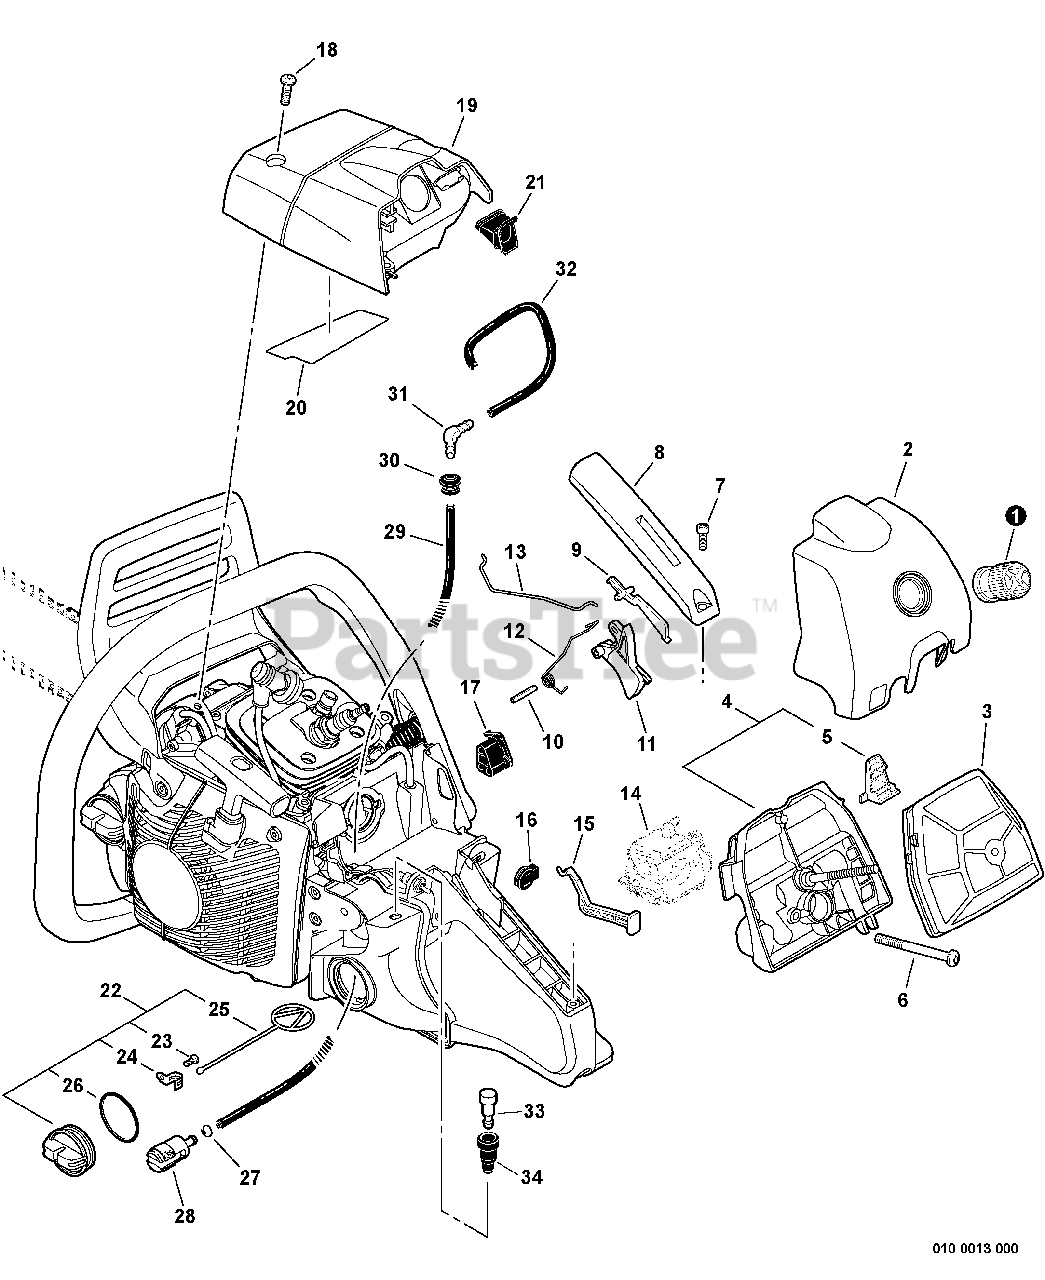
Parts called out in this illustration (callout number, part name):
1	KNOB, AIR FILTER COVER
2	COVER, AIR FILTER
3	FILTER ASSY, AIR
4	CASE ASSY, AIR FILTER
5	SHUTTER, AIR
6	BOLT, TORX 5×50
7	BOLT, TORX 4×12
8	COVER, HANDLE
9	LEVER, THROTTLE LOCKOUT
10	PIN, SPRING 4×25 SUS
11	TRIGGER, THROTTLE
12	SPRING, TORSION
13	ROD, THROTTLE
14	CARBURETOR
15	ROD, CHOKE
16	GROMMET, CHOKE
17	GROMMET, NEEDLE
18	BOLT, TORX 5×16
19	COVER, ENGINE
20	SHIELD, HEAT 75×32×0.15
21	PIPE, INTAKE
22	CAP ASSY, FUEL
23	SCREW, TAPPING 3×8
24	RETAINER, CONNECTOR
25	CONNECTOR, CAP L= 60 MM
26	O-RING 29
27	CLIP 6 MM
28	FILTER, FUEL
29	PIPE, FUEL 3×5×120 BLACK
30	GROMMET
31	CONNECTOR, PIPE Ø5.4
32	PIPE, FUEL 3×6×135L
33	VENT ASSY
34	GROMMET, VENT
